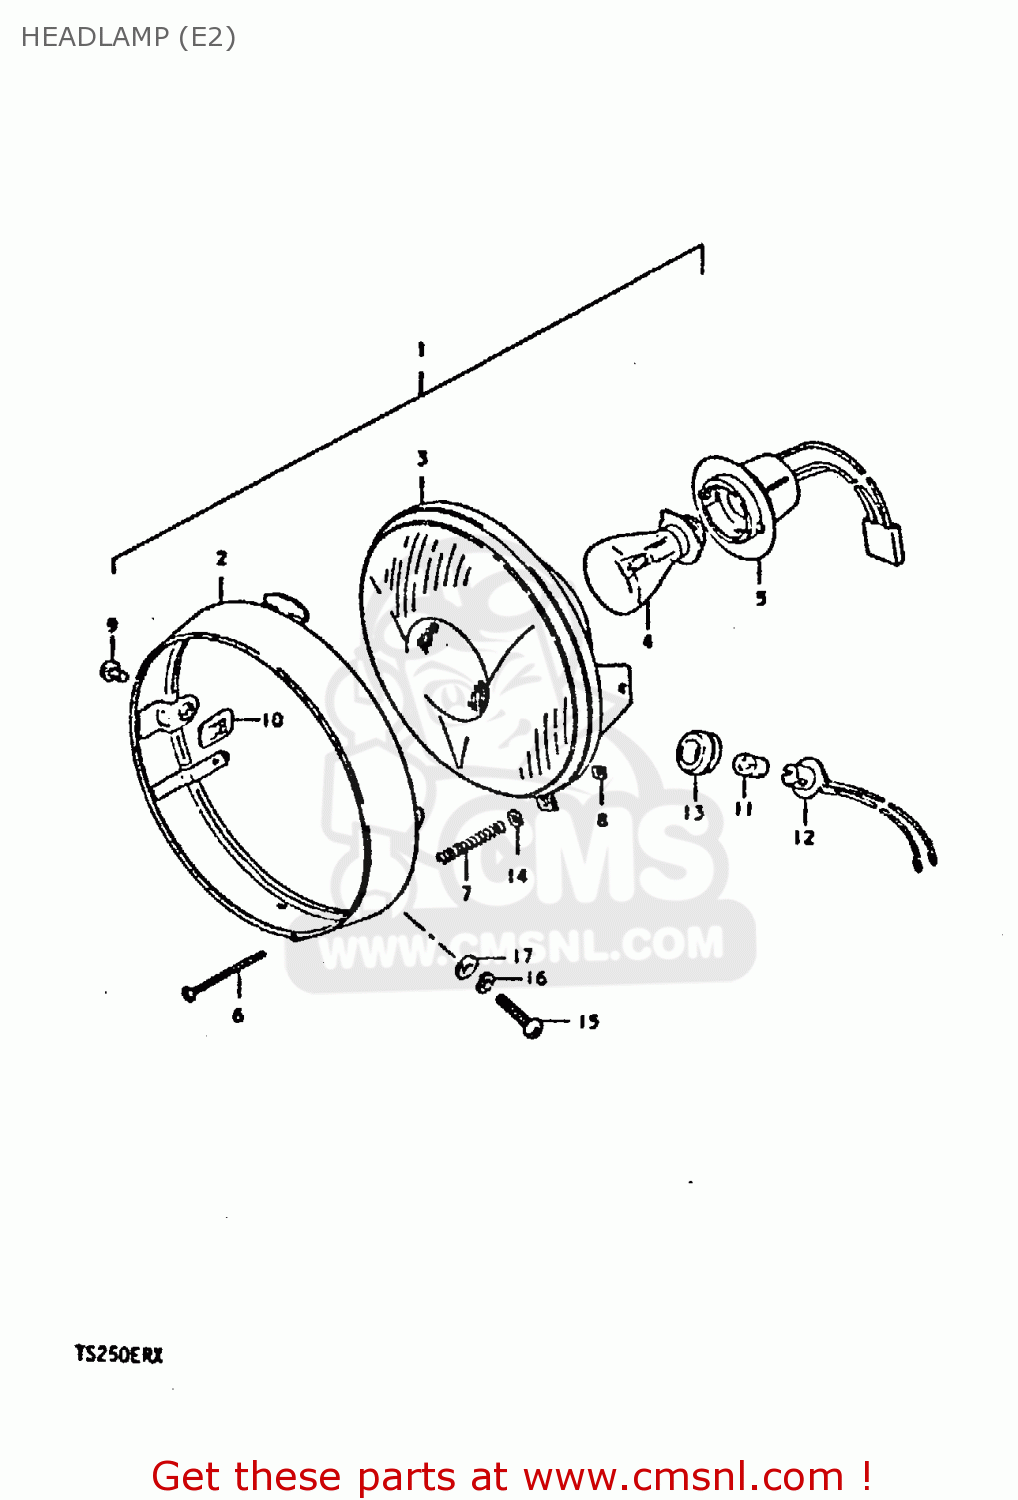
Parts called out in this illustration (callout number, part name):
1	HEADLAMP ASSY
2	RIM
3	UNIT
4	BULB(6V25/25W,STANLEY,A7007)
5	SOCKET
6	SCREW,HEADLAMP ADJUST
7	SPRING
8	NUT,HEADLAMP ADJUSTER
9	SCREW
10	NUT
11	BULB(6V/3W)
12	SOCKET
13	SEAL,PARKING BULB
14	WASHER
15	SCREW
16	LOCK WASHER
17	WASHER
